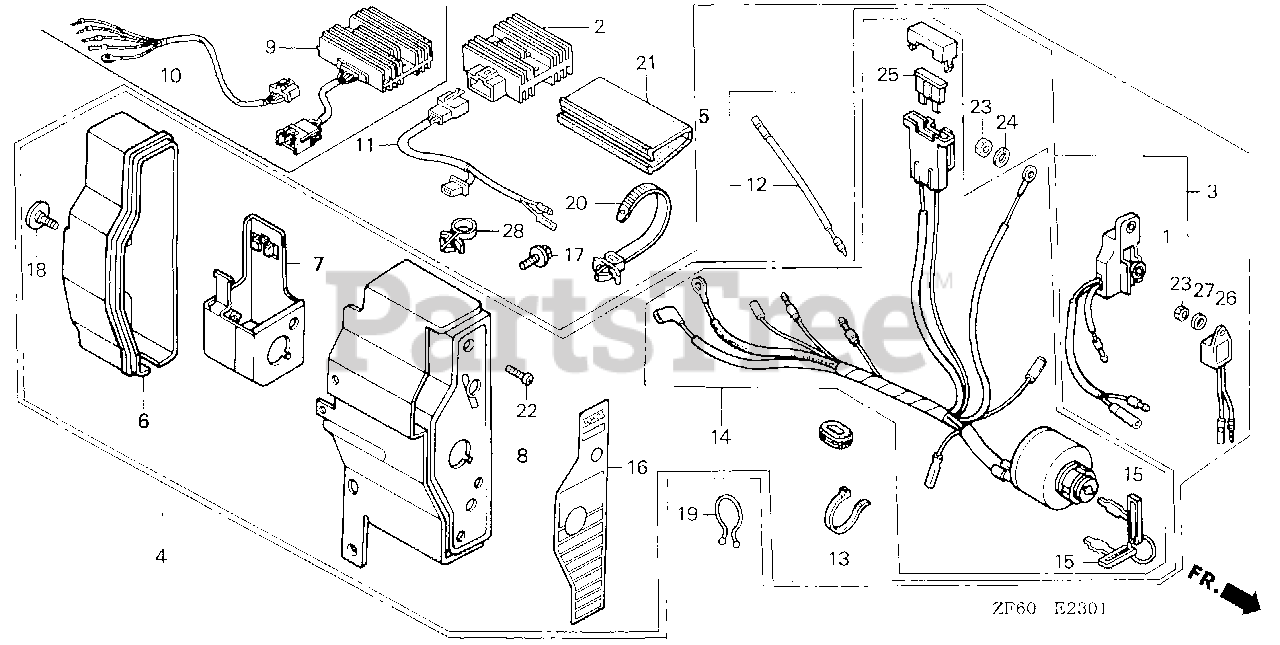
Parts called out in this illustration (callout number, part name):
5	BOX ASSY., CONTROL (18A) *R280* (EXP-ALERT) (POWER RED)
6	CASE, CONTROL
7	BRACKET, CASE MOUNTING
8	PANEL, CONTROL *R8* (BRIGHT RED)
8	PANEL, CONTROL *R280* (POWER RED)
12	SUB-WIRE HARNESS
14	SWITCH ASSY., COMBINATION (18A-CHARGE)
15	KEY (HONDALOCK)
16	MARK, CONTROL BOX (EXTERNAL-REGULATOR)
17	BOLT, FLANGE (6X12) (CT200)
18	SCREW, SPECIAL (6X12)
19	CLIP, PURSE LOCK
20	STRAP, CABLE (118MM) (BLACK)
21	TUBE, FASTENER (30MM)
22	SCREW, PAN (4X12)
23	NUT, HEX. (4MM)
24	WASHER, SPRING (4MM)
25	FUSE, BLADE (25A)
26	ALERT UNIT, OIL
27	WASHER, PLAIN (4MM)
28	HOLDER, STOP SWITCH WIRE
